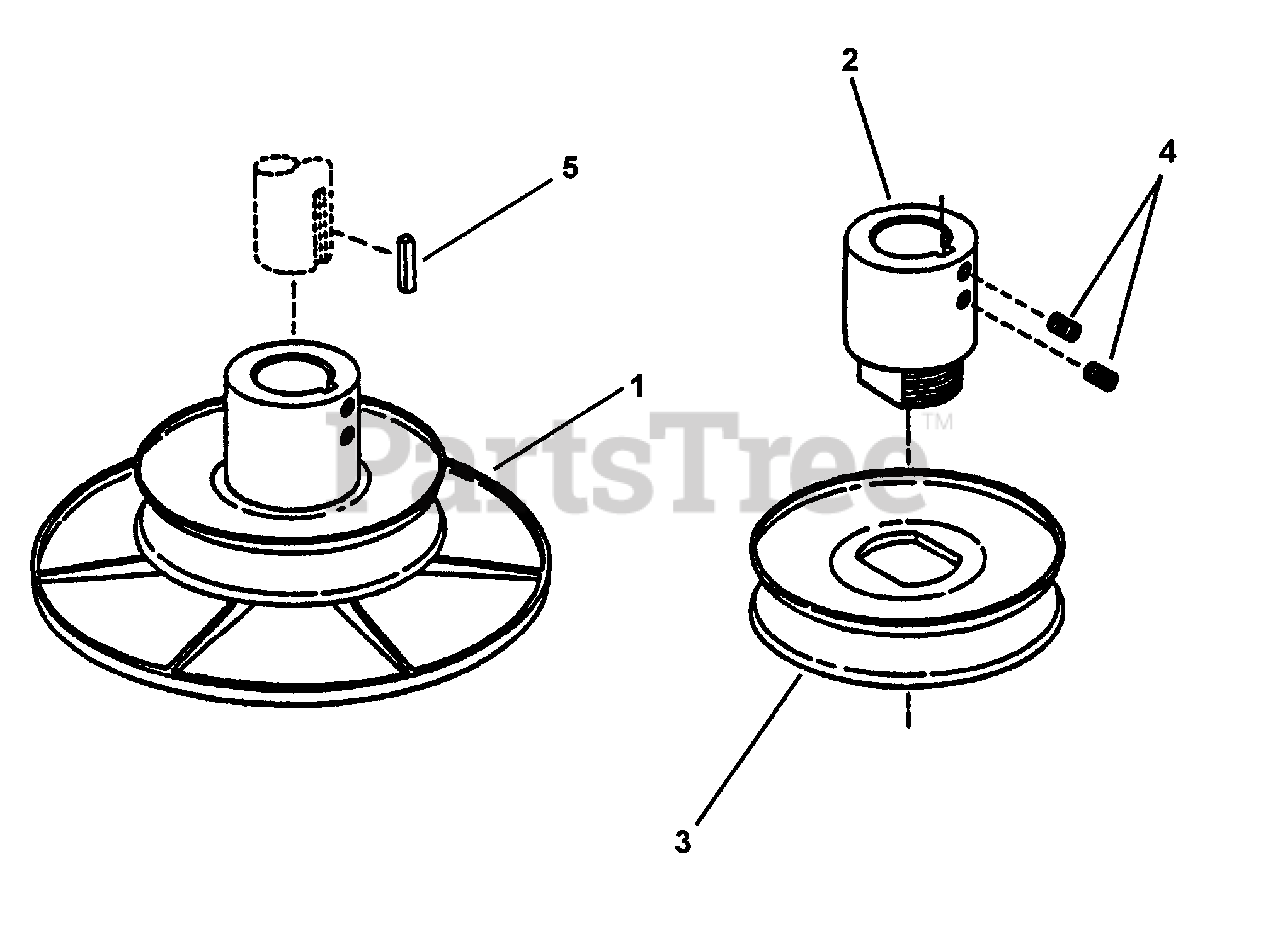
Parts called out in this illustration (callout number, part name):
1	ASSEMBLY, 5.18" O.D. Drive Disc
3	PULLEY, Drive
4	SCREW, 3/8-16 x 3/8" Set
5	KEY, 1/4" Square x 2"
